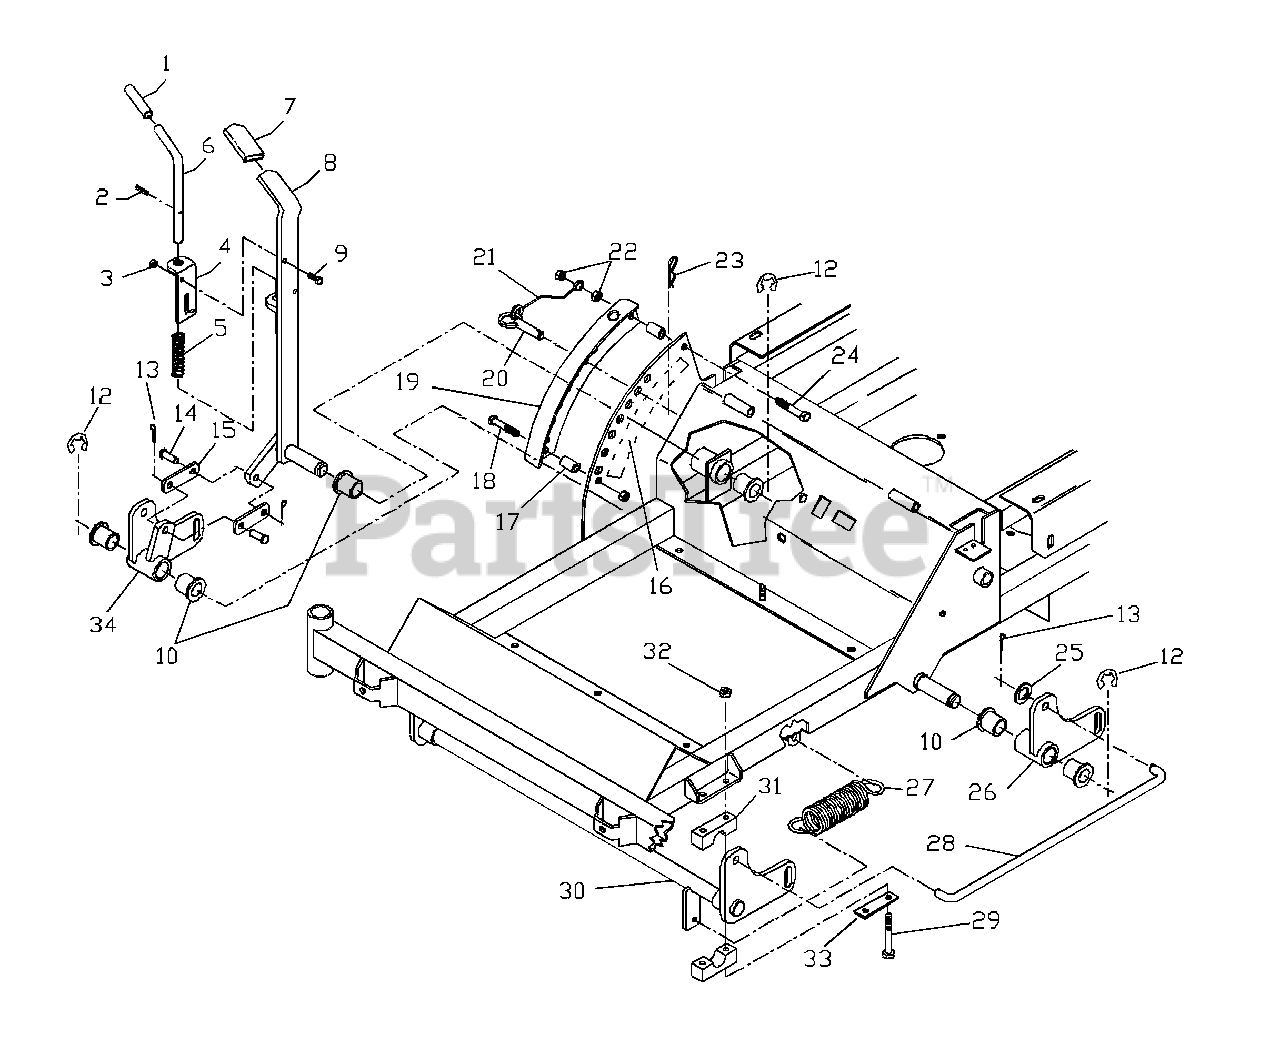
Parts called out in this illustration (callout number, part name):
2	3/16 X 1 ROLL PIN
3	NUT 1/4C CENTER LOCK
4	PIN MT, UPPER
8	LEVER WLDMT
9	1/4C X 3/4 HCS
10	FLANGED BUSHING
11	BELLCRANK WLDMT - RT
12	7/8 'E' RING
13	1/8 X 3/4 COTTER PIN
14	3/8 X 1 1/8 CLEVIS PIN
16	DECAL, LOCATOR
18	HCS 3/8C X 2
19	LOCATOR WLDMT
22	NUT 3/8C CENTERLOCK
23	#4 HAIRPIN
24	HCS 3/8C X 2 1/4
25	1/2 MACH. BUSHING
26	BELLCRANK WLDMT - LT
29	HCS 5/16C X 2 3/4
30	LIFT WLDMT
31	LIFT BLOCK
32	NUT 5/16C CENTERLOCK
33	REINF. PLATE
34	BELLCRANK WLDMT.
